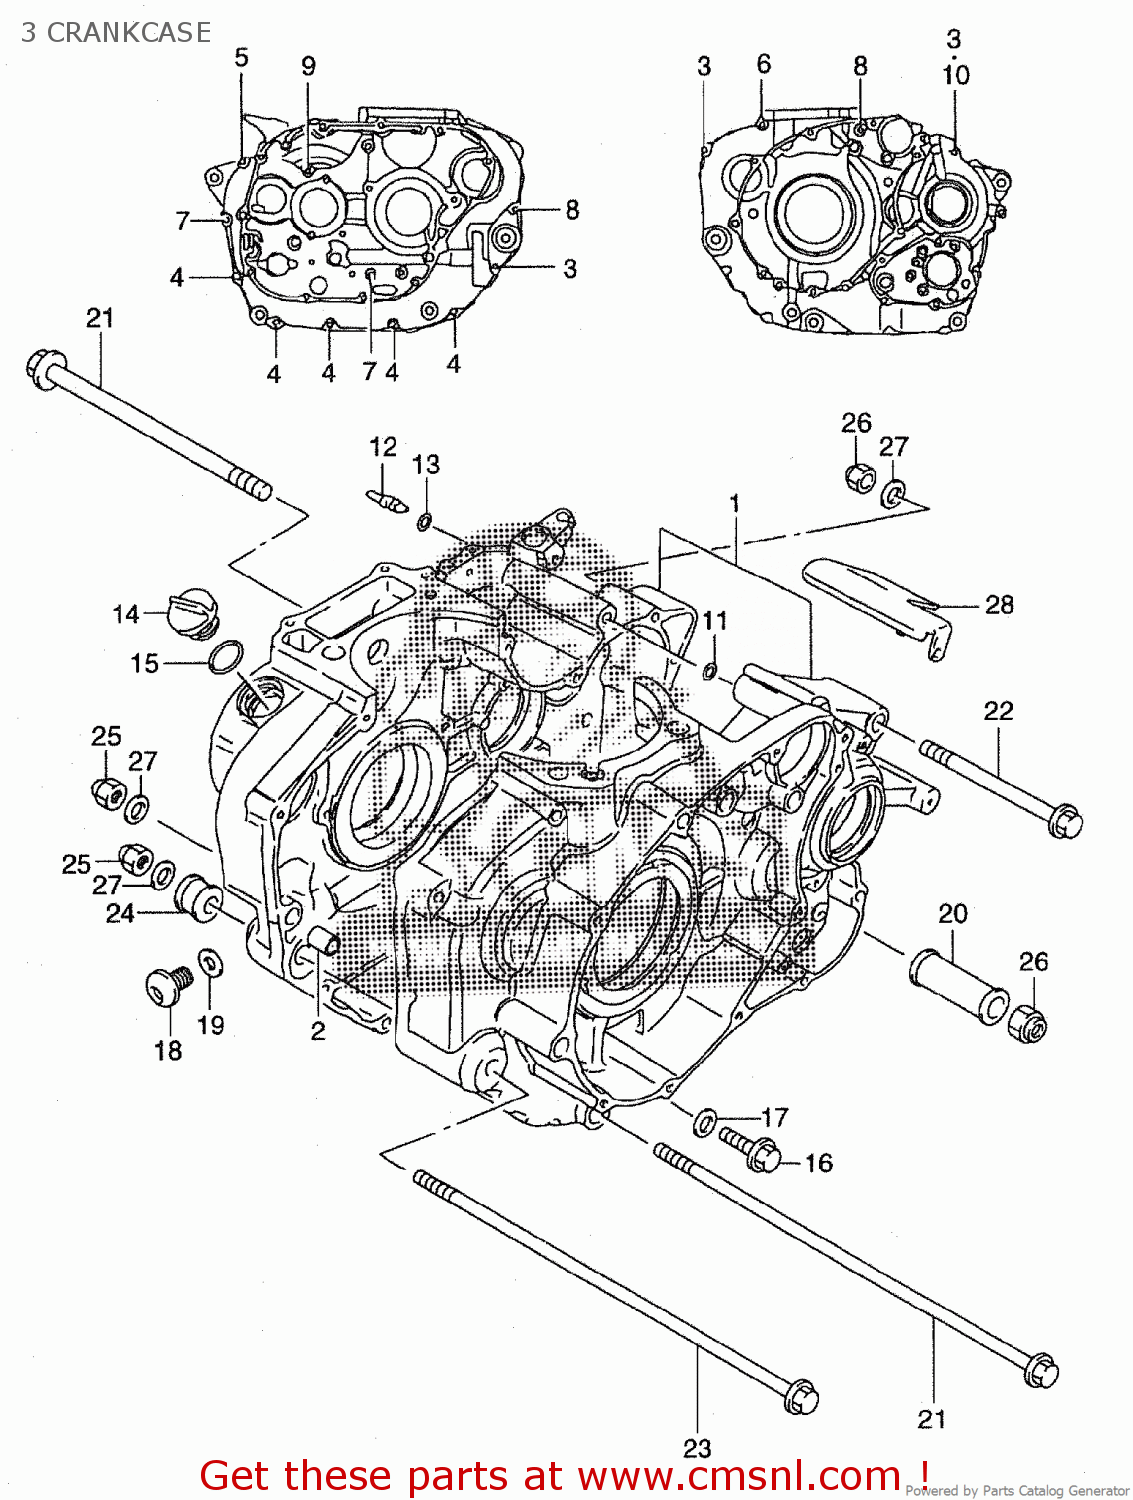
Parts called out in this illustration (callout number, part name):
1	CRANKCASE SET
2	PIN(8.4X11X20)
3	BOLT
4	BOLT
5	BOLT
6	BOLT
7	BOLT
8	BOLT
9	BOLT
10	GASKET(5.8X11X1.2) (NAS)
11	O RING(D:2.4,ID:9.6)
12	JET,OIL GALLERY(18)
13	O RING(D:1.2,ID:4)
14	PLUG(20X10)
15	O RING(D:3.1,ID:16.8)
16	PLUG,12X20
17	GASKET(12.1X16.2X3.7) (NAS)
18	PLUG(14X12)
19	GASKET(13.8X18.8X4.8) (NAS)
20	SPACER,ENGINE MOUNT NO
21	BOLT 10X230
22	BOLT(10X105)
23	BOLT (10X215)
24	SPACER,ENGINE MOUNT(L20)
25	NUT
26	NUT
27	WASHER
